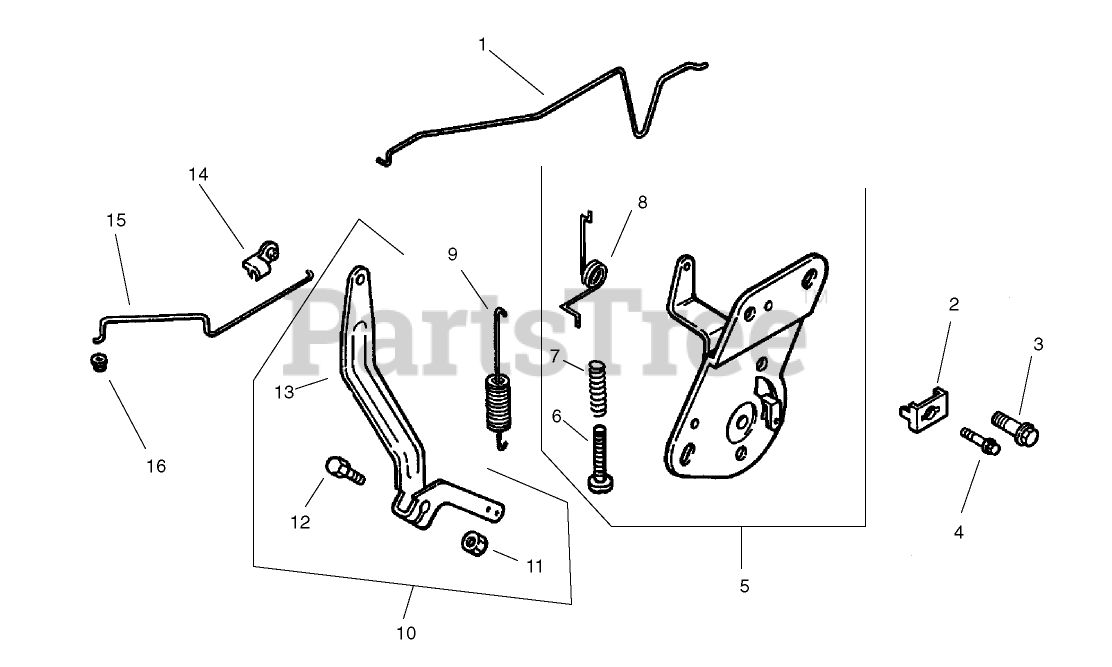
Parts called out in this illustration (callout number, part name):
1	Linkage-Choke
2	CLAMP-CABLE
3	SCREW-FLANGE, THREAD FORMING (M5X0.8X16)
4	Screw-Socket, 6 Lobed (Thread Forming, M6x1.0x20)
5	Control, speed assembly (Includes 6-8)
6	Screw-SPH,M4x0.7x25
7	Spring-Control, Speed
8	Spring-Return, Choke
9	Spring-Governor
10	Kit, Governor Lever (Incl 10-12)
11	Nut-Flange, Hex (1/4-20)
12	Bolt-Square Neck, Round Head (1/4-20x1)
13	Lever-Governor
14	BUSHING-RETAINING, LINKAGE
15	Linkage-Throttle
16	BUSHING-LINKAGE, THROTTLE
